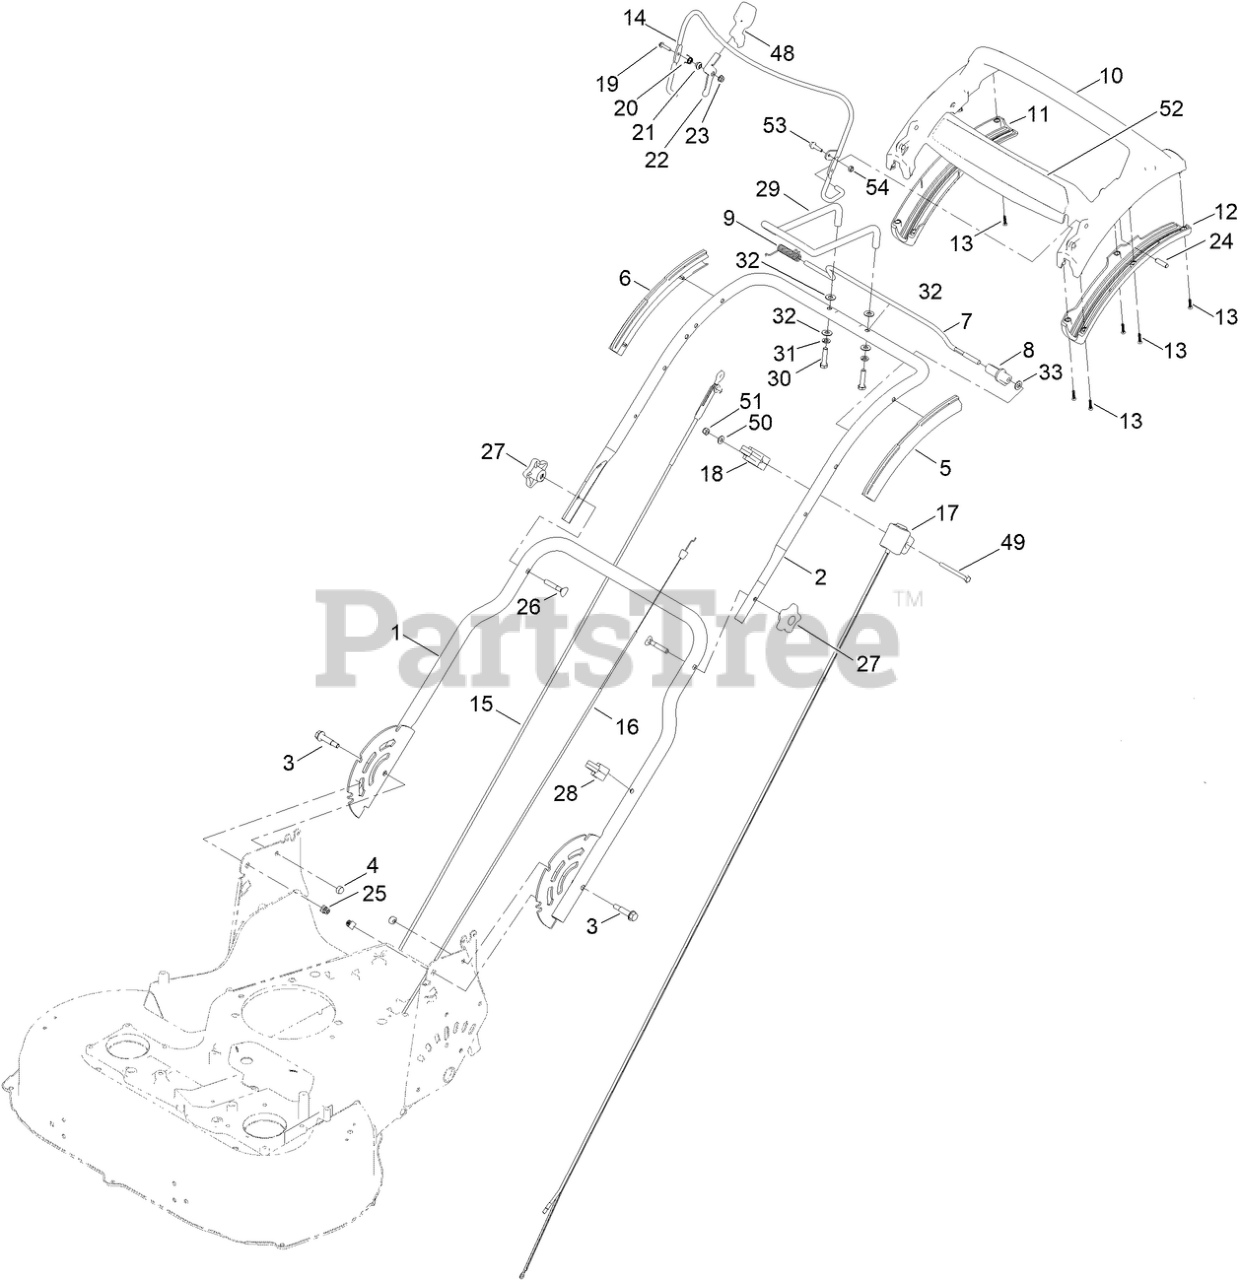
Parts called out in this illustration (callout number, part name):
1	HANDLE-LOWER, ASM
2	HANDLE-UPPER
3	BOLT-SHOULDER, HHF
4	NUT-LOCK, NI
5	GUIDE-CURVED, LH (RWD)
6	GUIDE-CURVED, RH (RWD)
7	ROD-CONTROL, TRACTION
8	LEVER-TRACTION, RWD
9	SPRING-TORSION
10	HANDLE-PERSONAL PACE, CURVED
11	BOTTOM-HANDLE, RH
12	BOTTOM-HANDLE, LH
13	SCREW-PPH
14	BAIL-BRAKE [BLACK]
15	CABLE-BRAKE
16	CABLE-TRACTION
17	SWITCH HOUSING ASM
18	ANCHOR-CABLE, RWD
19	SCREW-HWH
20	SPRING-TORSION
21	SPACER
23	NUT-LOCK, FLANGE
24	PIN-HANDLE, PP
25	PLUG-SQUARE
26	SCREW-HANDLE
27	KNOB-HANDLE
28	GUIDE-CABLE
29	HANDLE-ASSIST, STEEL
30	SCREW-HH
31	WASHER-LOCK
32	WASHER
33	WASHER-PLAIN
49	SCREW-HH
50	WASHER-FLAT
51	NUT-LOCK, NI
52	DECAL-HANDLE, PP
53	SCREW-SHOULDER
54	NUT-HEX
